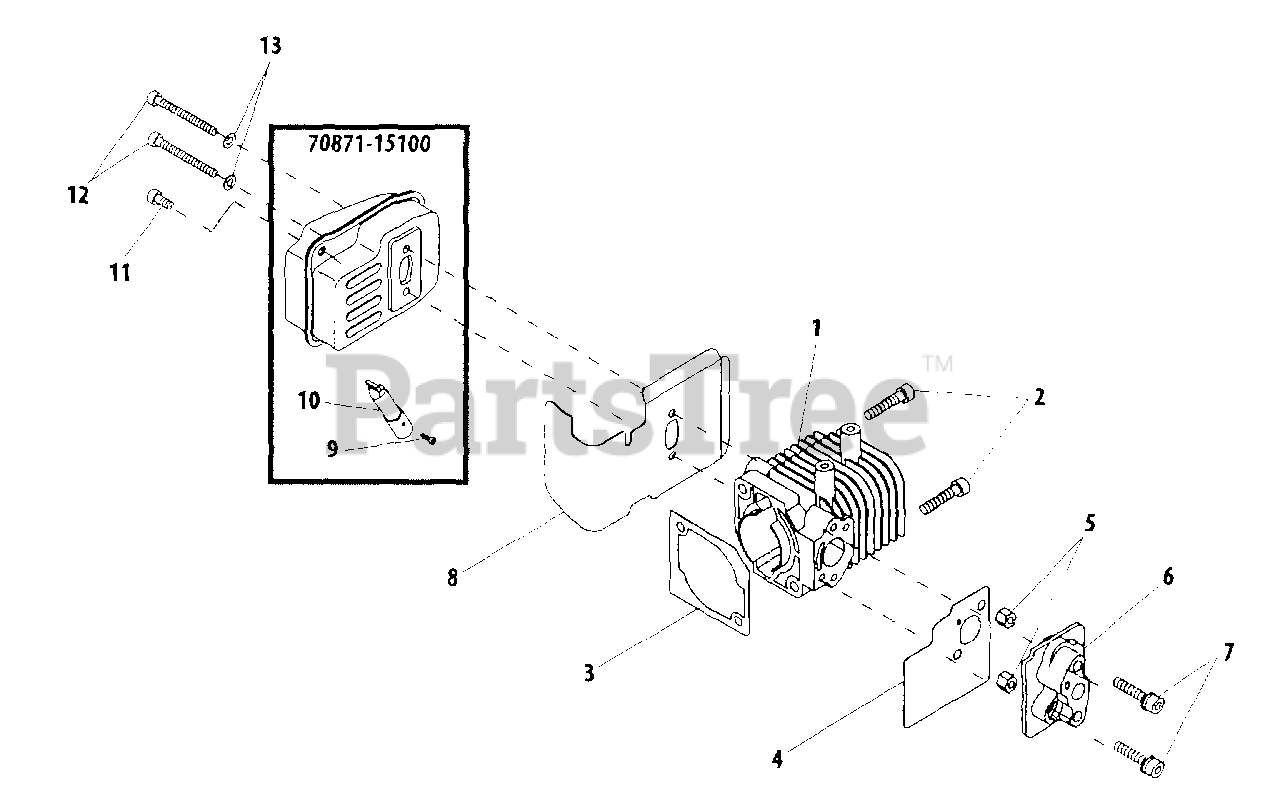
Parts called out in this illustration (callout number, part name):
1	CYLINDER
2	SCREW - 5X25
3	GASKET, CYLINDER
4	SHIELD, INTAKE
5	NUT
6	INSULATOR
7	SCREW - 5X25
8	SHIELD, INTAKE
9	SCREW - 3X6
10	SCREEN, SPARK ARRESTOR
11	SCREW - 5X12
12	SCREW - 5X50
13	WASHER - 5
70871-15100	MUFFLER ASSY
